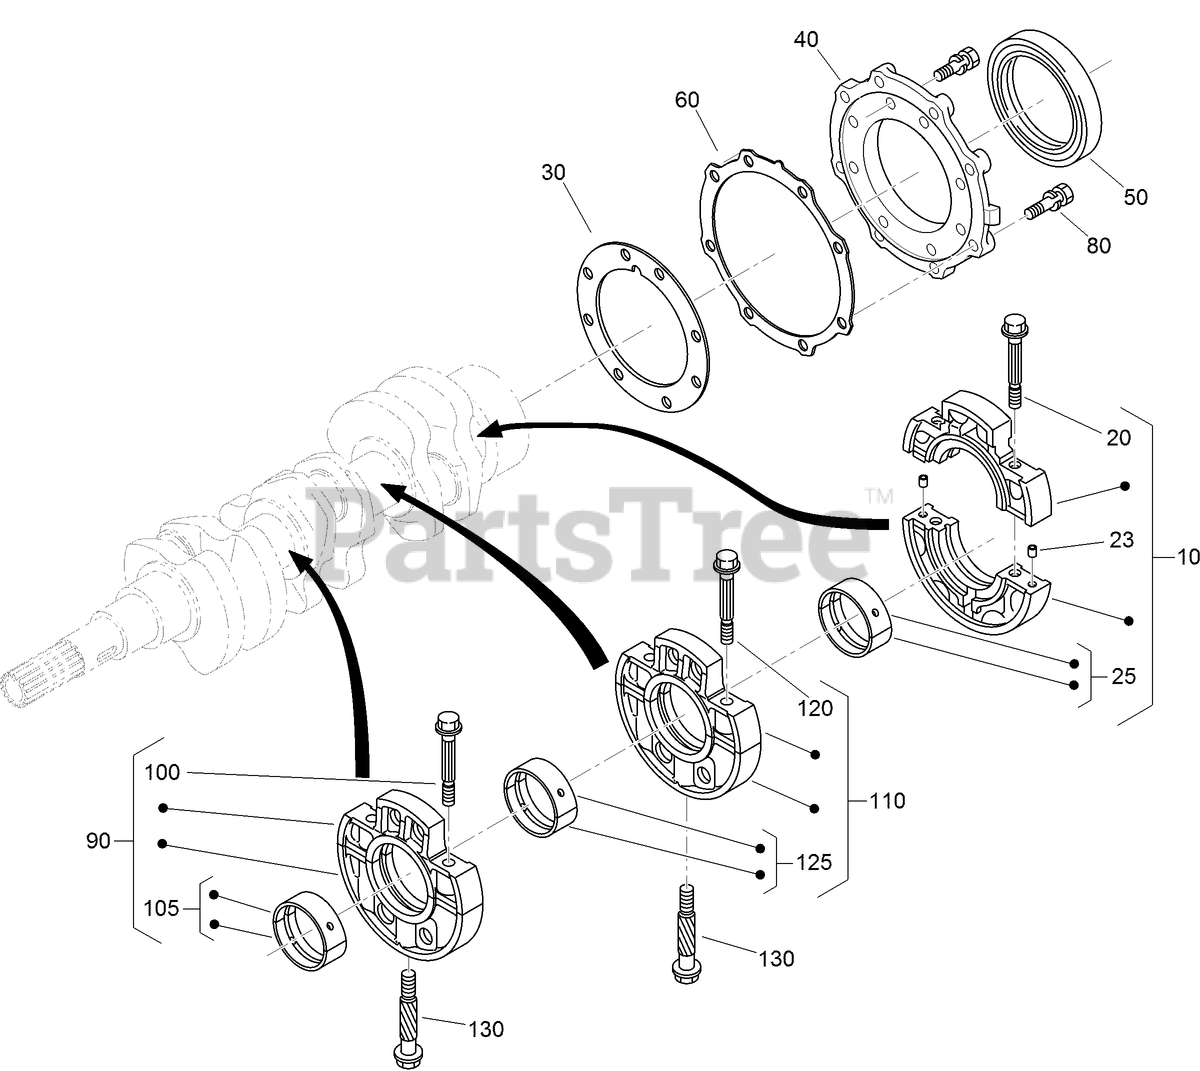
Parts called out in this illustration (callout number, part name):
10	WHEEL BEARING CASE ASM
20	BOLT-FLANGE
23	PIN-STRAIGHT
25	CRANKSHAFT METAL ASM (STD)
25	CRANKSHAFT METAL ASM (-0.20MM)
25	CRANKSHAFT METAL ASM (-0.40MM)
30	GASKET-CASE, BEARING
40	COVER-CASE, BEARING
50	SEAL-OIL
60	GASKET-COVER, CASE
90	MAIN BEARING CASE ASM
100	BOLT-CASE, BEARING
105	CRANKSHAFT METAL ASM (STD)
105	CRANKSHAFT METAL ASM (-0.20MM)
105	CRANKSHAFT METAL ASM (-0.40MM)
110	MAIN CASE BEARING ASM
120	BOLT-CASE, BEARING
125	CRANKSHAFT METAL ASM (STD)
125	CRANKSHAFT METAL ASM (-0.20MM)
125	CRANKSHAFT METAL ASM (-0.40MM)
130	BOLT-CASE, BEARING
